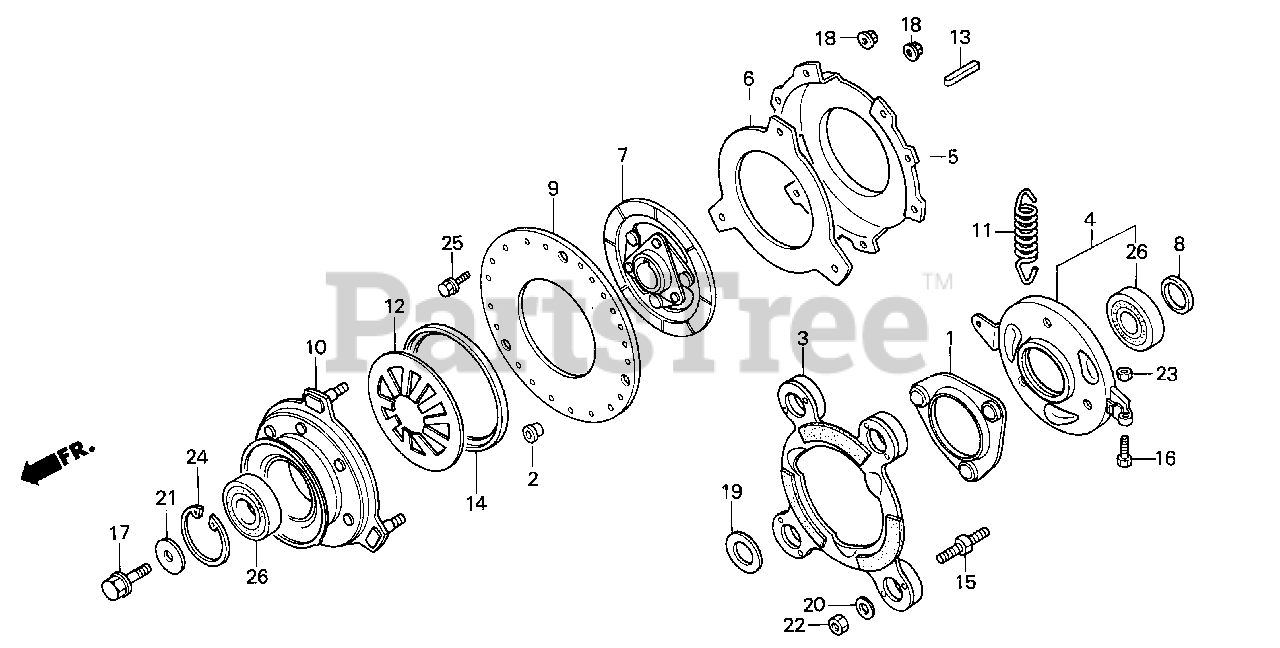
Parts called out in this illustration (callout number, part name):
1	RETAINER, FR. BALL
2	BUSH, RR. CLUTCH
3	BRAKE ASSY.
4	PLATE, BALL CONTROL
5	PLATE, BRAKE
6	PLATE, CLUTCH SIDE
7	DISK, FRICTION
8	COLLAR, DISTANCE (25MM)
9	PLATE, CLUTCH
10	PULLEY, DRIVEN
11	SPRING, CLUTCH RETURN
12	SPRING, CLUTCH
13	KEY (7X7X30)
14	SEAT, CLUTCH SPRING
15	BOLT, SPECIAL
16	BOLT, HEX. (8X30)
17	BOLT, SPECIAL (8X25)
18	NUT, U (6MM)
19	SHIM (25X38X1.3) (B)
19	SHIM (25X38X1.4) (D)
19	SHIM (25X38X1.5) (F)
19	SHIM (25X38X1.6) (H)
19	SHIM (25X38X1.1) (L)
19	SHIM (25X38X1.2) (M)
20	WASHER, THRUST (8.5)
21	WASHER (8MM)
22	NUT, HEX. (8MM)
23	NUT, HEX. (8MM)
24	CIRCLIP (INNER) (47MM)
25	BOLT, FLANGE (6X16)
26	BEARING, RADIAL BALL (6005UU)
